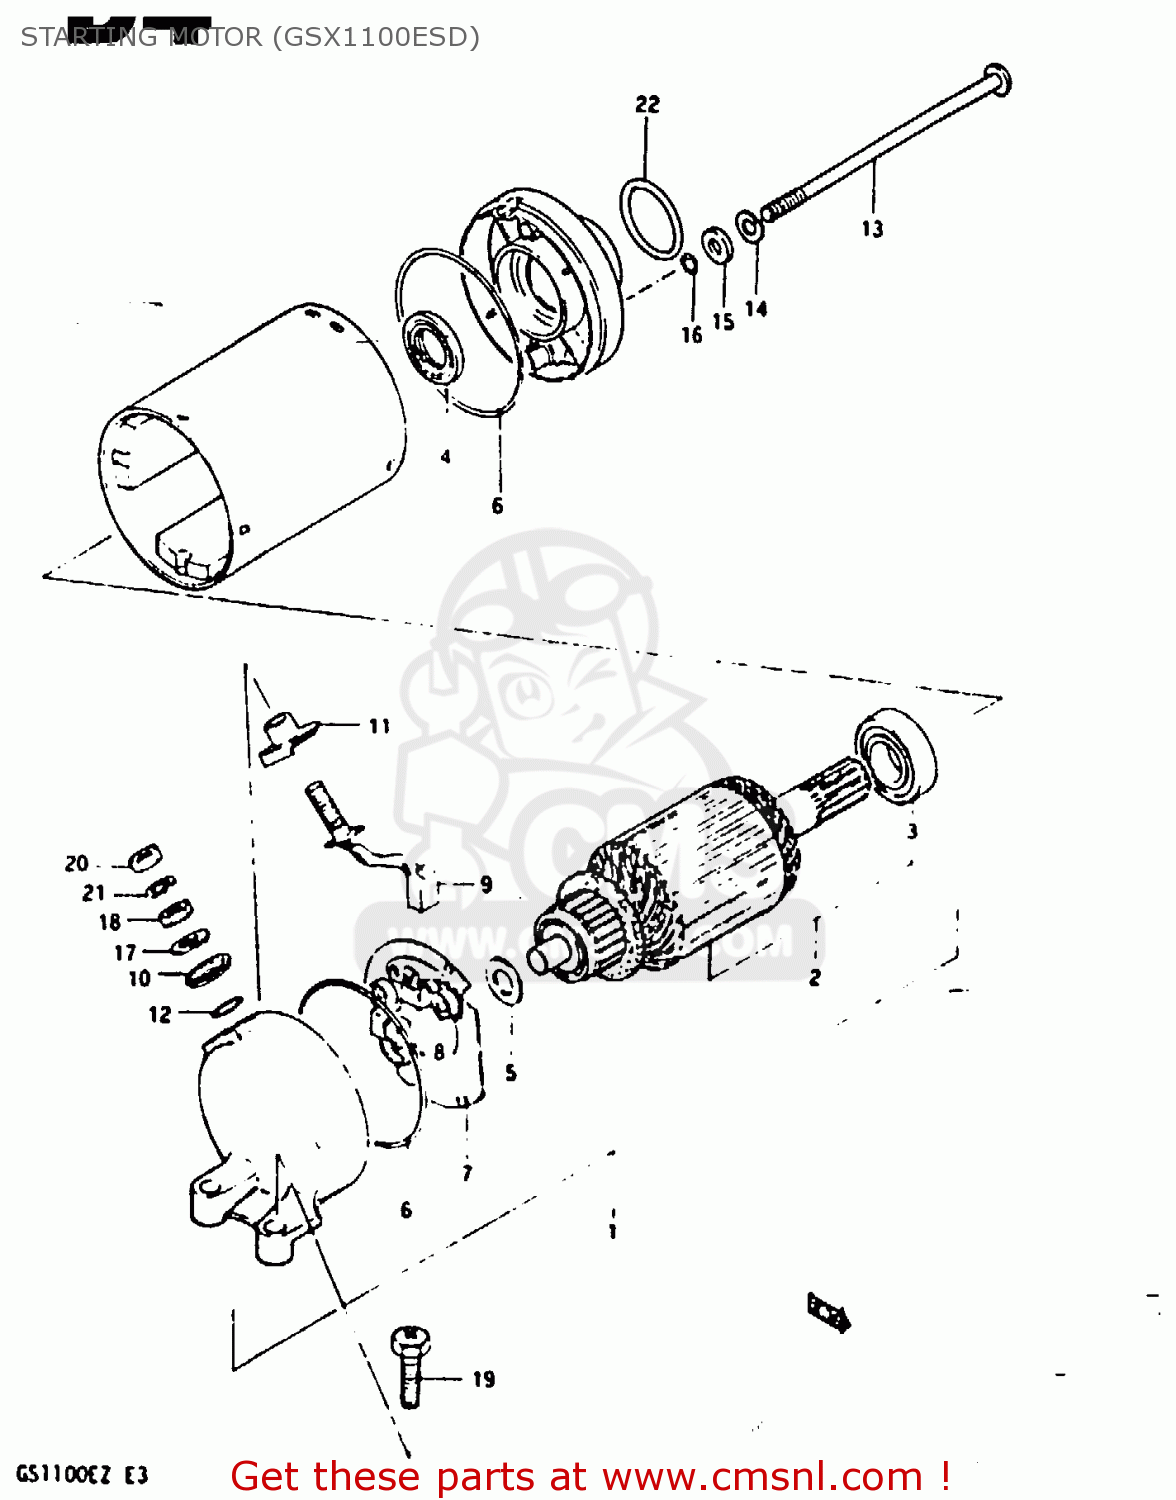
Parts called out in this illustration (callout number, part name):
1	MOTOR ASSEMBLY,STARTING
2	ARMATURE
3	BEARING
4	SEAL,OIL
5	SHIM,ARMATURE
6	O RING
7	HOLDER,BRUSH
8	SPRING
9	BRUSH SUB ASSY,STARTING MOTOR
10	BUSHING
11	BUSH,B
12	O RING
13	BOLT
14	LOCK WASHER
15	WASHER
16	O RING
17	WASHER
18	NUT 6MM
19	SCREW (6X25)
20	NUT 6MM
21	LOCK WASHER
22	O RING(D:3,ID:24.5)
